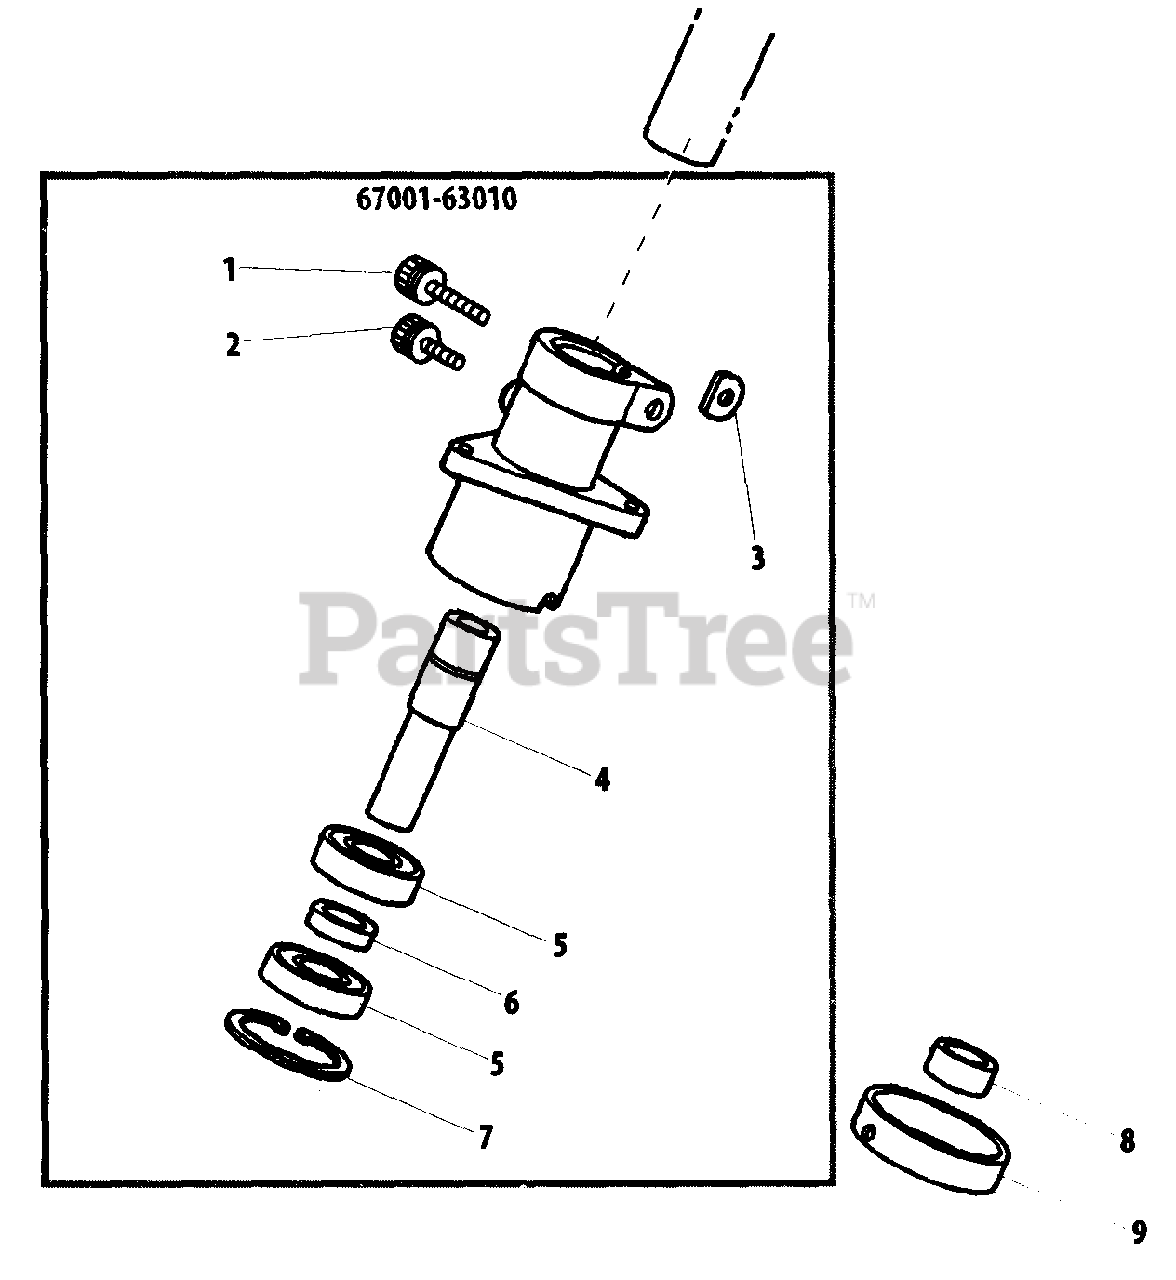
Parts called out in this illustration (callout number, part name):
1	BOLT M5×25
2	BOLT
3	D-WASHER
4	SHAFT
5	BEARING, BALL 6001 DDU
6	COLLAR (A)
7	RING, SNAP Ø28
8	COLLAR (B)
9	HOLDER
67001-63010	GEAR CASE ASSY
